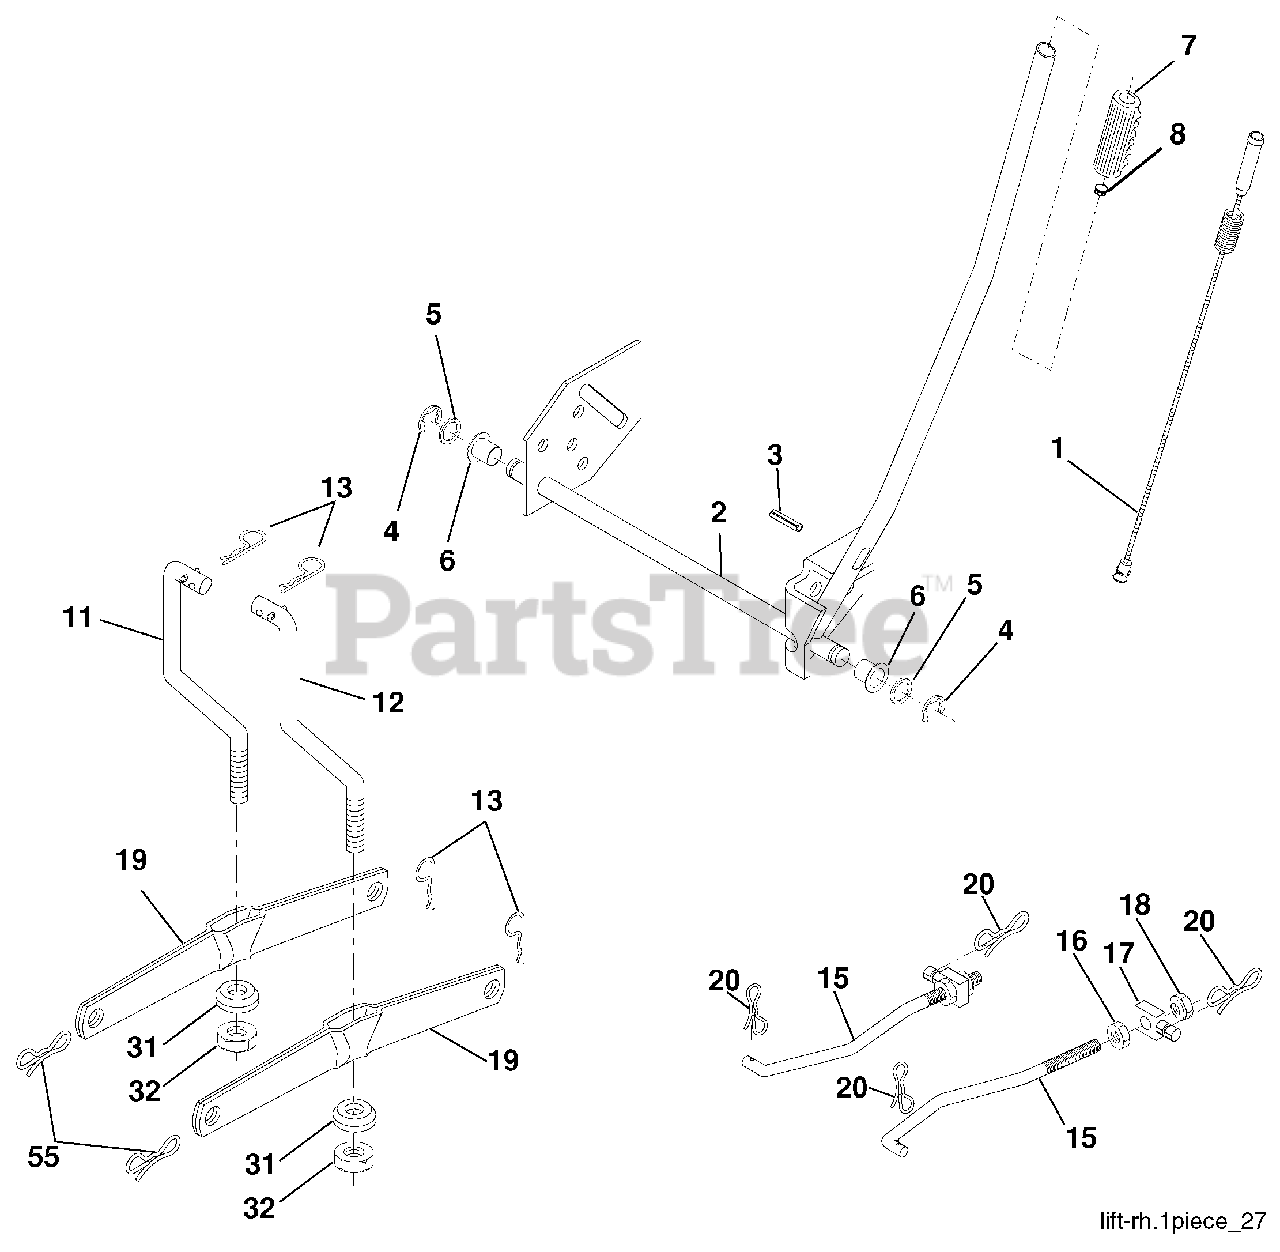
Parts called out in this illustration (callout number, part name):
1	Wire Asm Inner/Sprg w/plunger
2	Shaft Asm Lift RH
3	Pin Groove 1 500 Zinc
4	E Ring #5133-62
5	Washer 21/32 x 1 x 21 Ga.
6	Bearing Nylon Blk 629 Id
7	Grip Handle Bicycle Matte Blk
8	Button Plunger Black
11	Link Lift LH Fixed Length
12	Link Lift RH Fixed Length
13	Retainer Spring
15	Link Front
16	Nut Jam Hex 1/2-13 unc
17	Trunnion
18	Nut Lockw/Wsh 1/2-13 unc
19	Arm Suspension Rear
20	Pin Cotter 7/16 Bow Tie Lock
31	Bearing Pvt Lift
32	Nut Crownlock 3/8-24
55	Pin Cotter 5/16 Bowtie Lock
